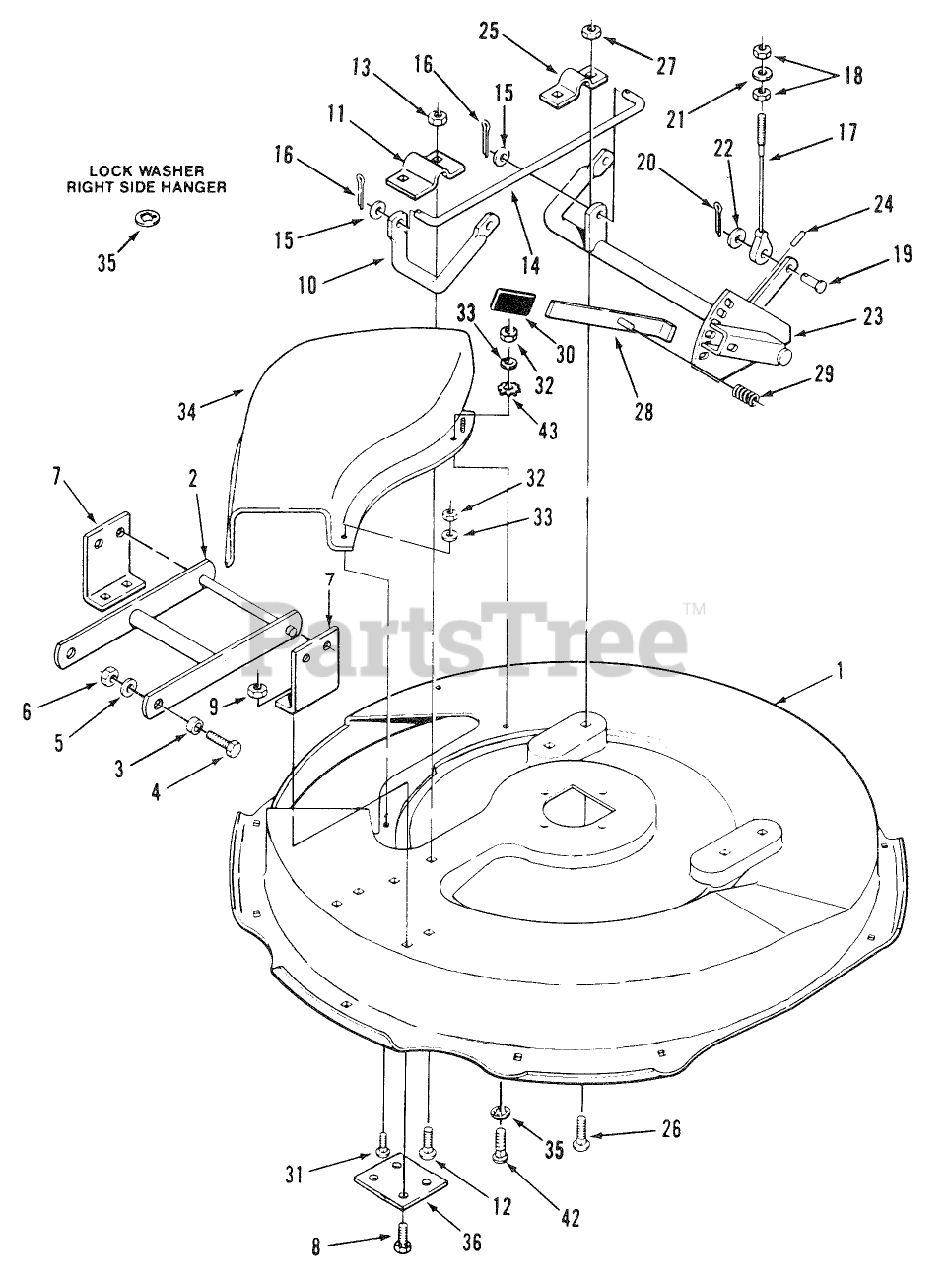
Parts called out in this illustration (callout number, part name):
3	SPACER
7	BRKT FRONT MOWER *R
17	CABLE MOWER SUPPORT
21	WASHER 5/16 SAE
24	SPIROL PIN
25	CLAMP
28	LEVER ASSY
29	SPRING-COMPRESSION
